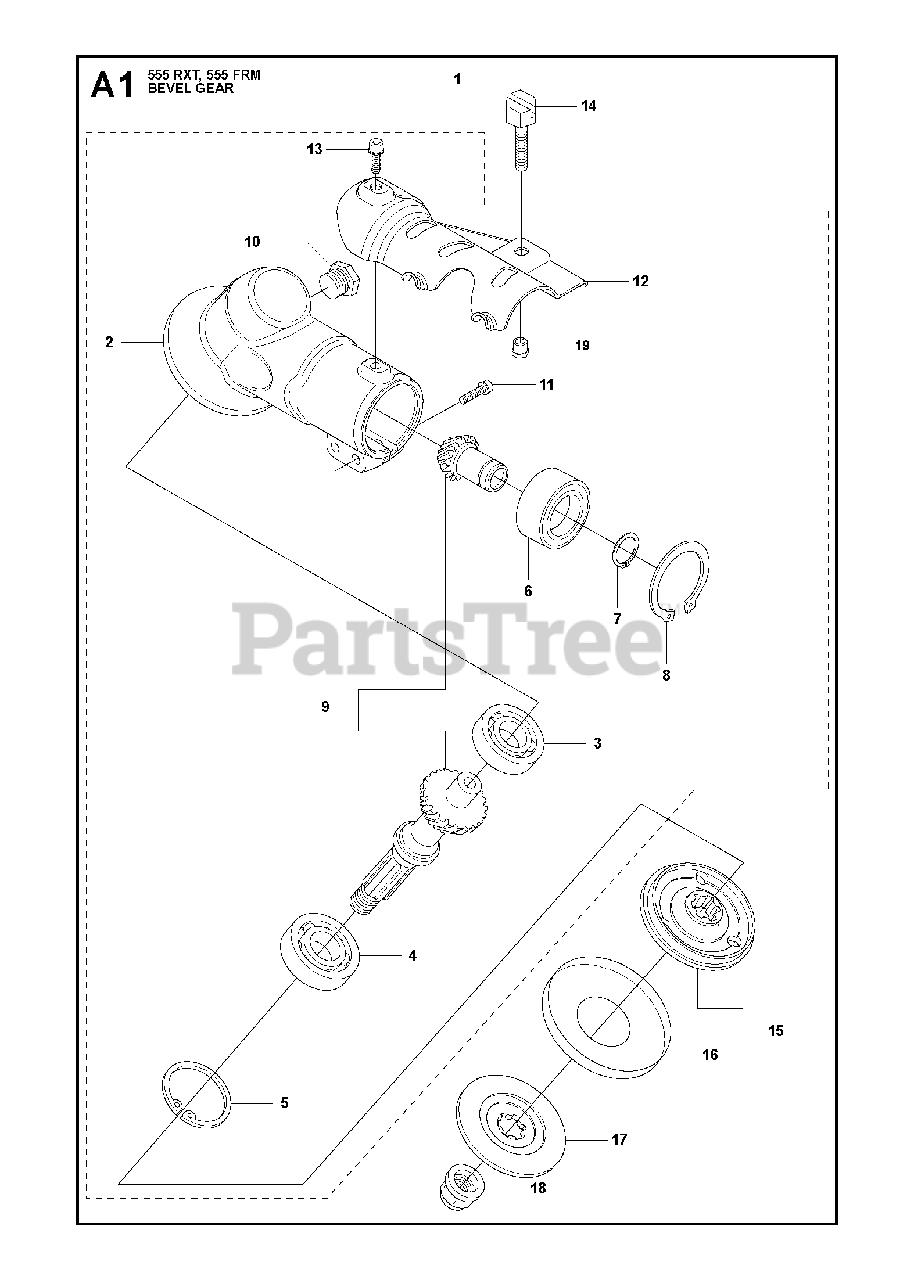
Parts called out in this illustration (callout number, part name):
1	BEVEL GEAR SPARE PART
2	GEAR HOUSING
3	BALL BEARING
4	BALL BEARING
5	RETAINING RING SGH 35
6	BEARING
7	RETAINING RING SGA 15
8	RETAINING RING
9	BEVEL GEAR
10	PLUG
11	SCREW
12	ATTACHMENT PLATE UPPER ASSY
13	SCREW
15	CARRIER
16	GRASS SEALING
17	SUPPORT FLANGE
18	BLADE NUT
19	SPACING SLEEVE
